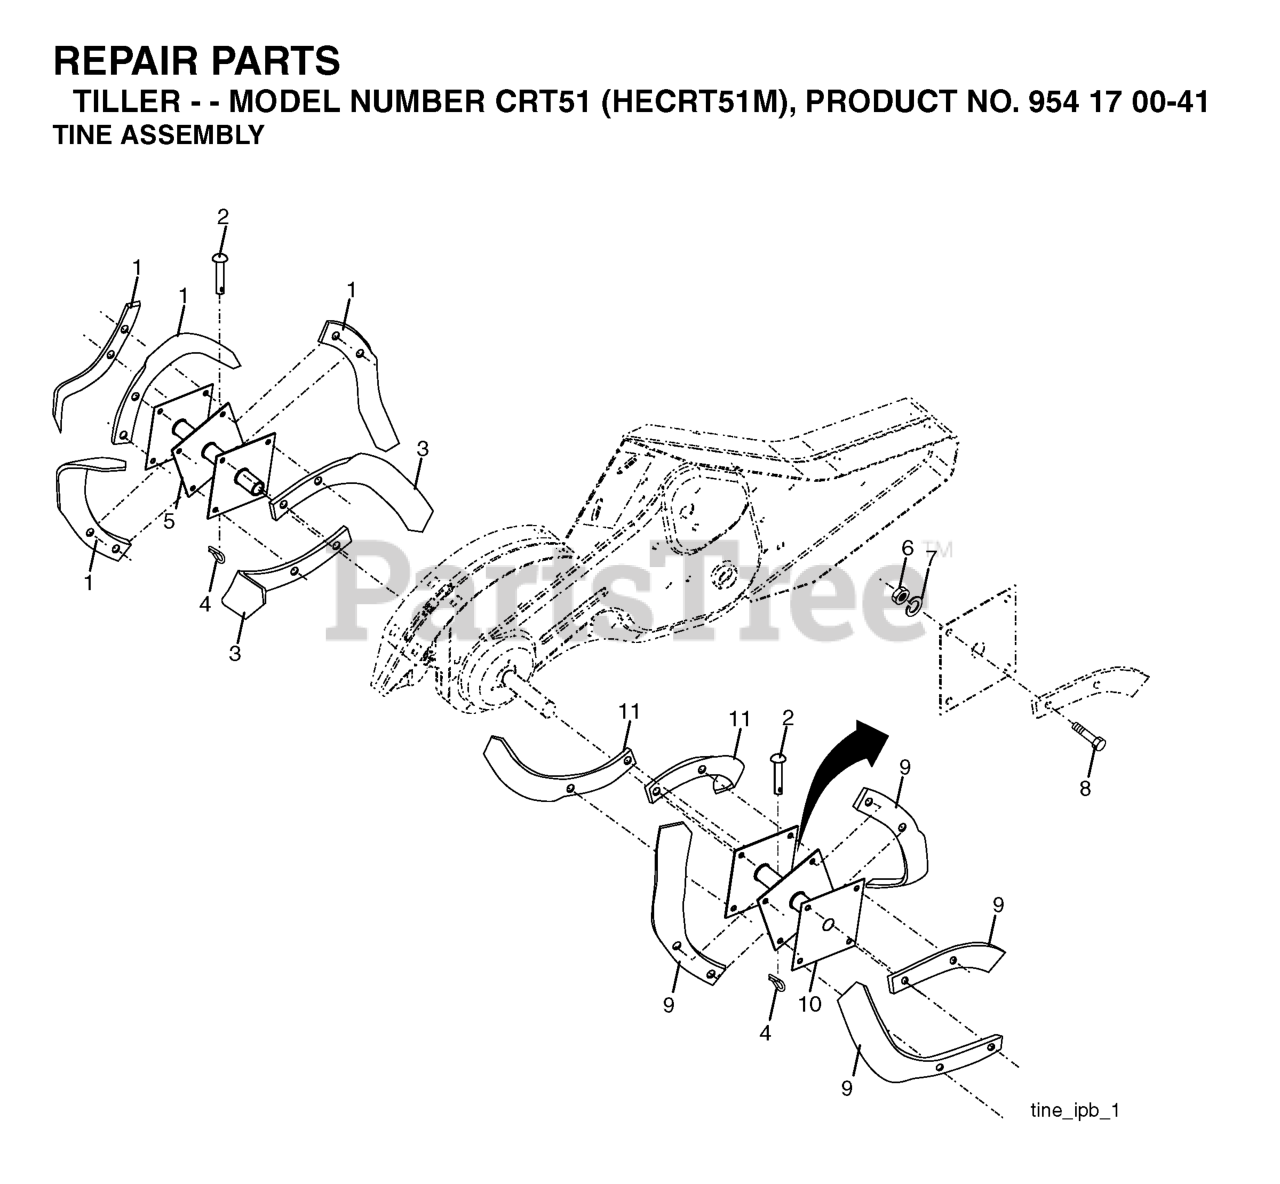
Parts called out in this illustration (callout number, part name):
1	TINE TI
2	PIN RETAINING SCREW
3	TINE.LH.12"(72L)
4	SPRING RETAINER
5	HUB.&.PLATE.ASM.LH
6	NUT
7	WASHER, LOCK 3/8
8	BOLT.HEX.001X20.37-24X1.ZINC
9	TINE TI
10	HUB & PLATE ASM RH
11	TINE.RH.12"(72R)
